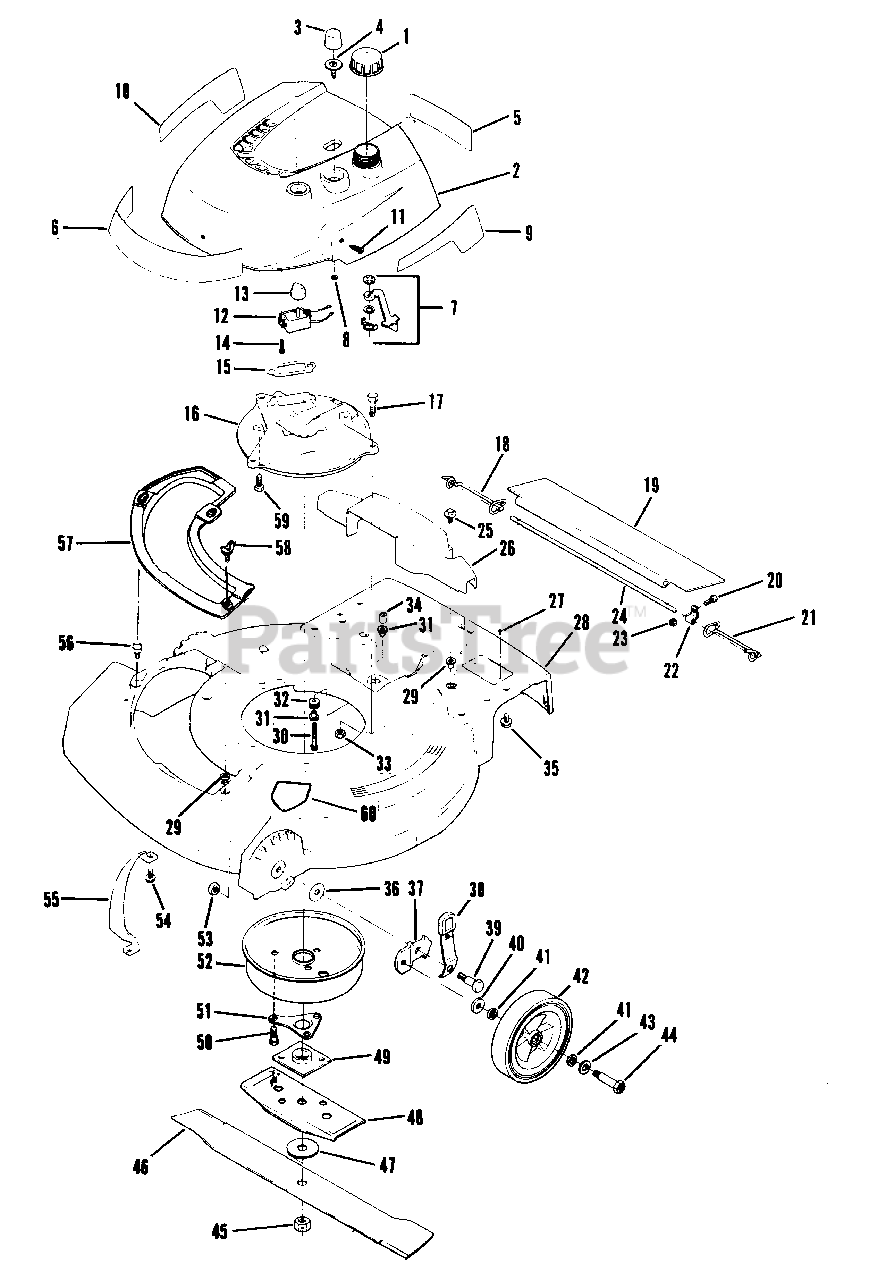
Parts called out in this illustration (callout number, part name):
1	Fuel Cap
2	Shroud-Engine
3	Bulb-Primer
4	Base-Primer
5	Decal-Instructions
6	Decal-Lawn-Boy
7	Fuel Shut-Off Assembly
8	Nut-Primer Base
9	Decal-L.H. 21"
10	Decal-R.H. 21"
11	Screw-Shroud Mounting
12	Switch-On-Off
13	Knob-Switch
14	Screw
15	Gasket-Exhaust
16	Plate-Muffler
17	Screw-Muffler Plate to Housing
18	Spring-R.H.
19	Shield-Trailing
20	Screw
21	Spring-L.H.
22	Clamp
23	Nut
24	Rod-Trailing Shield
25	Screw-Axle Cover Mounting
26	Cover-Drive Axle
27	Screw-Model Plate Mounting
28	Housing
29	Grommet
30	Screw-Sems
31	Spacer
32	Grommet
33	Nut-Muffler Plate to Housing
34	Spacer
35	Screw-Handle Bracket to Housing
36	Washer
37	Bracket-Wheel Height Adjustment
38	Knob & Spring Assembly
39	Shoulder Bolt
40	Washer
41	Washer-Felt
42	Wheel-Front
43	Washer
44	Bolt-Wheel-Front
45	Nut-Blade
46	Blade-21"
47	Washer-Blade
48	Stiffener-Blade
49	Collar & Plate Assembly
50	Screw
51	Support-Crankshaft
52	Muffler Cover Assembly
53	Nut
54	Screw-Sems
55	Toe Bar
56	Screw-Sems-Plate & Chute Mounting
57	Cover Plate
58	Wing Screw
59	Screw-Muffler Plate to Block
60	Decal-Blade Contact Warning
